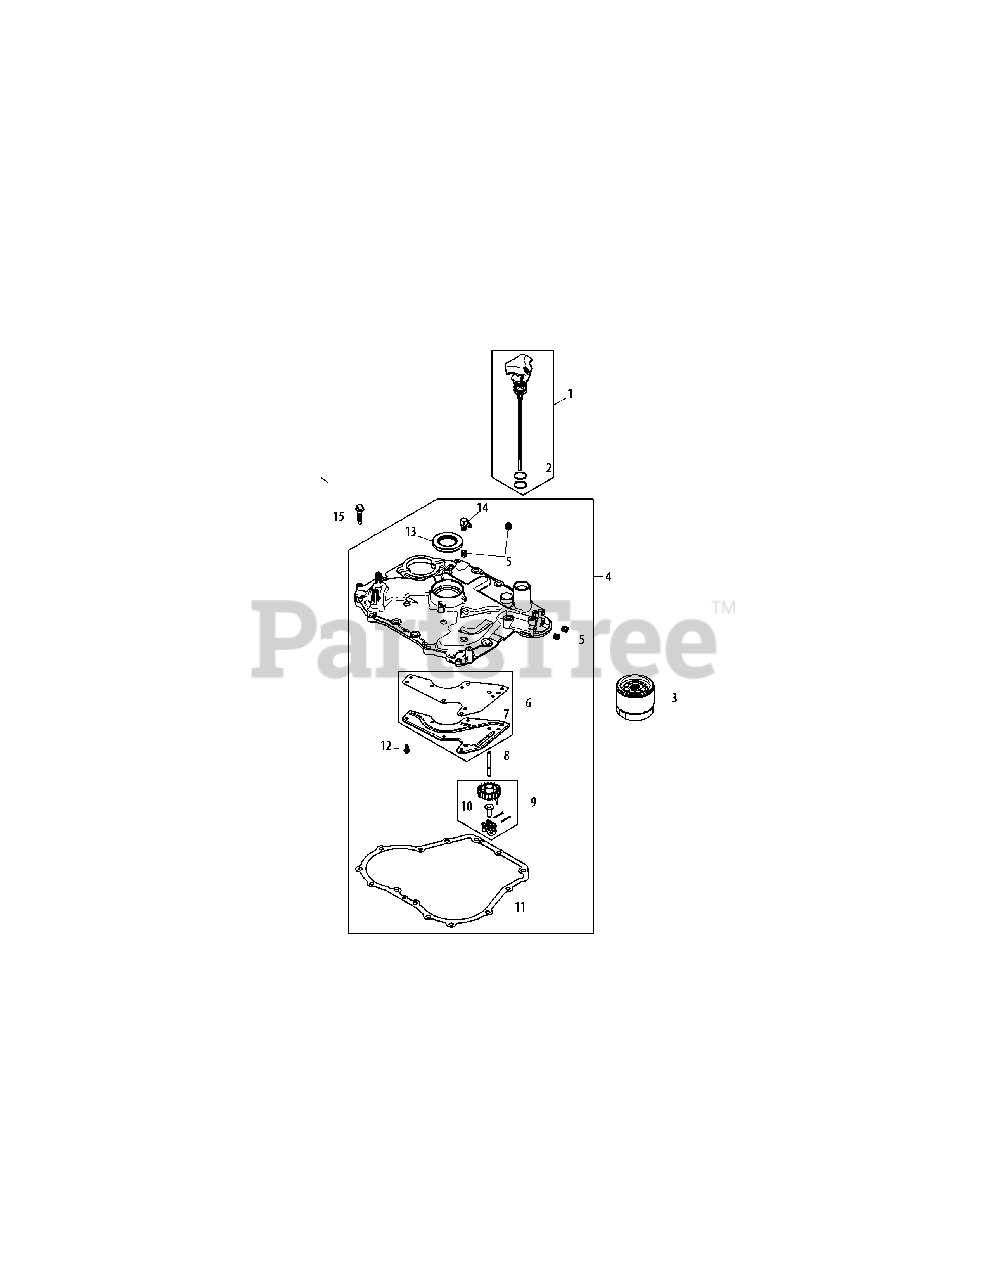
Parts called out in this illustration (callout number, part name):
1	Dipstick Ass’y-Std Yellow (Incl. 2)
2	O-Ring
4	Closure Plate Assembly (Incl. 5-14)
5	Ctsk Pipe Plug, 1/8
6	Oil Passage Cover Kit (Incl. 7)
7	Oil Passage Gasket
8	Governor Cross Shaft
9	Governor Gear Assembly
10	Governor Regulating Pin
11	Closure Plate Gasket
12	Flange. Thd. Frm. Screw, M5 X 0.8
13	Oil Seal
14	90° Hose Connector
15	Hex Flange Screw, 1/2
